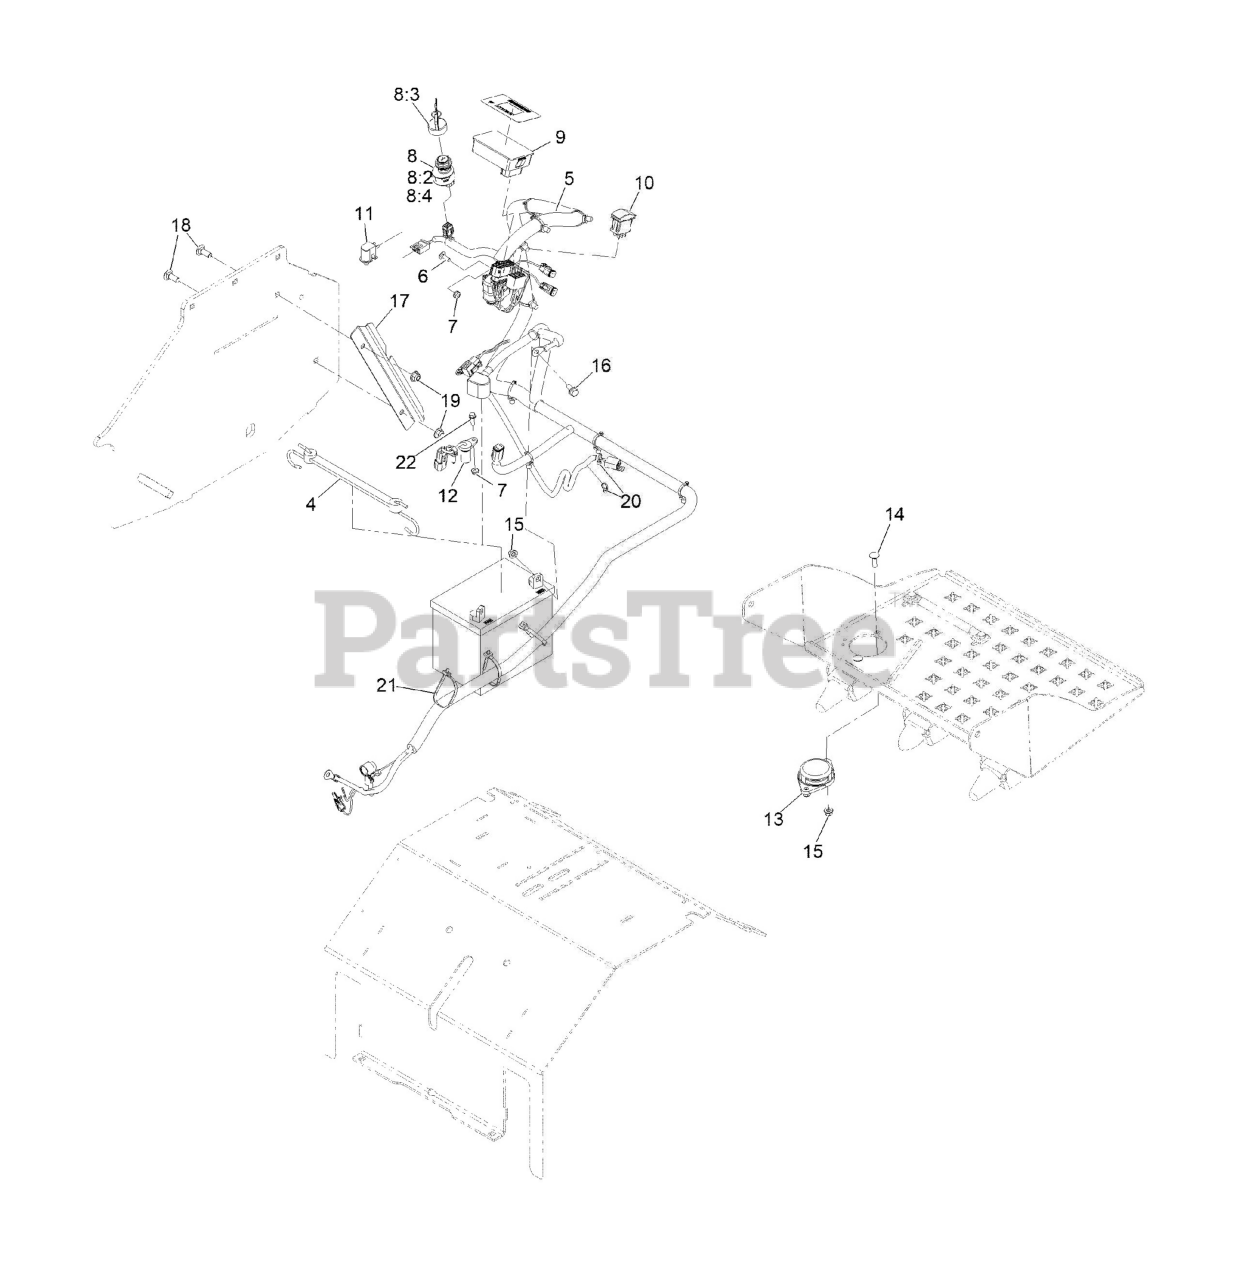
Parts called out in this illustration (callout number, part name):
4	HOLDDOWN-BATTERY
5	HARNESS-WIRE
6	BOLT-CARR
8	IGNITION SWITCH ASM
8:2	NUT-MOUNTING
8:3	IGNITION KEY SET
8:4	WASHER-BACKUP
9	Hour Meter ASM
11	SWITCH-BAIL
12	SENSOR-QUADRATURE
13	SWITCH-SEAT
14	BOLT-CARR
15	NUT-HF, NI
16	SCREW-HHF
17	GUARD-HARNESS
18	BOLT-CARR
19	NUT-HF, NI
20	TIE-CABLE
21	TIE-CABLE
22	SCREW-HWH
